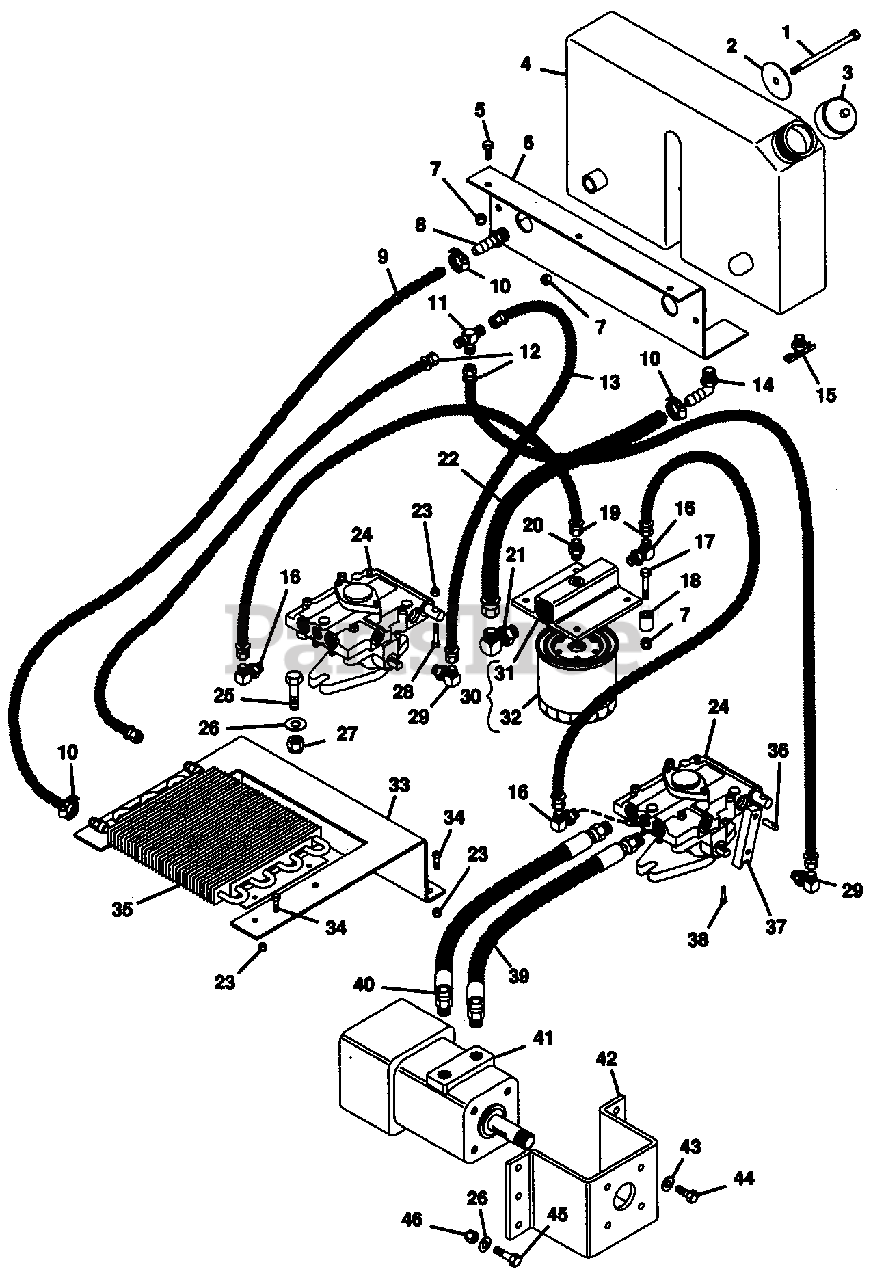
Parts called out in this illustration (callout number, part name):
1	BOLT, HEX 5/16-18 X 3.50
2	WASHER, FLAT .344 X 3.0 X .060
3	CAP, TANK
4	TANK, HYDRAULIC OIL
5	BOLT, HEX 5/16-18 X .75
6	BRACKET, HYD. TANK MTG.
7	NUT, LOCK 5/16-18
8	ADAPTOR, MALE
9	HOSE, OIL COOLER TO TANK
10	CLAMP, .88 DIA. HOSE
11	ADAPTOR, TEE
12	HOSE, HYD. VALVE TO TANK
13	HOSE, PUMP TO TEE
14	FITTING, MALE ELBOW 1/2 X 1/2
15	COCK, DRAIN
16	ADAPTOR, 2503-4-4
17	BOLT, HEX 5/16-18 X 2.00
18	BUSH., ST. .328 X .462 X 1.00 STL.
19	HOSE, OIL FILTER TO PUMP
20	ADAPTOR, 0503-4-4
21	ADAPTOR, P-H #2503-8-8
22	HOSE, TANK TO OIL FILTER
23	NUT, LOCK 1/4-20
24	PUMP, VARIABLE DISPLACE
25	BOLT, HEX 3/8-16 X 1.125
26	WASHER, FLAT .406 X .812 X .065
27	NUT, LOCK 3/8-16
28	BOLT, HEX 1/4-20 X 2.00
29	ADAPTOR, 2503-6-6
30	ASSEMBLY, SPIN-ON LUBE
31	ASSEMBLY, HEAD
33	BRACKET, OIL COOLER
34	BOLT, HEX 1/4-20 X .750
36	PIN, DOWEL
37	ARM, PUMP ACTUATING
38	SCREW, CAP 10-24 X .75 HEX SOCKET
39	ASM, HOSE WHEEL MOTOR TO PUMP
40	ASM, HOSE WHEEL MOTOR TO PUMP
41	MOTOR, HYDRAULIC WHEEL
42	BRACKET, WHEEL MOTOR
43	WASHER, LOCK 3/8 REG.
44	BOLT, HEX .38/16 X .75 PL GR5
45	BOLT, HEX 3/8-16 X 1.00
46	NUT, LOCK 3/8-16
